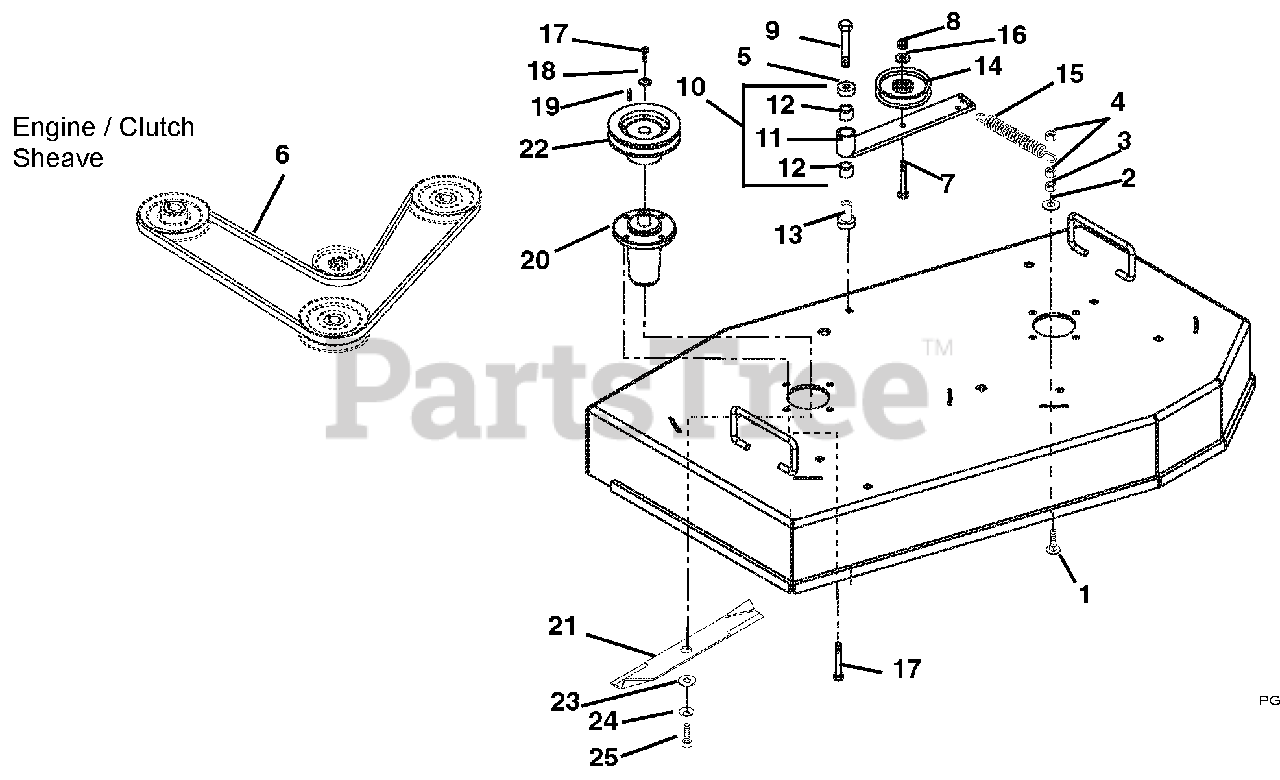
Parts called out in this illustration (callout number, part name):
1	@BLT-RDHDSQNK .38-16X1.50 G5YZ
2	@WSHR-LK .38X.094 REG YWZC
3	@NUT-HEX .38-16 YWZC
4	@NUT-LK-CTR .38-16 YWZC
5	WSHR-FL-STL .515X1.625X.250 YZ
6	V-BELT, HB-WRAPPED
7	@BLT-RDHDSQNK .38-16X3.00 G5YZ
8	@NUT-LK-CTR .38-16 YWZC
9	@BLT-HEX .50-13X3.75 GR5 YWZC
10	ASSEMBLY - IDLER PIVOT ARM
11	WMT - IDLER PIVOT ARM
12	BSHG, 1.00 X 1.125 X 1.937
13	BEARING, PEDESTAL
14	IDLER-FLAT 4.00X.38 (2.00 W)
15	SPRING, EXTENSION
16	SEAL, IDLER BEARING
17	BLT-HEX .38-16X1.0 GR8 YZ EP30
18	WSHR,FLT STL.406X1.50X.245YWZC
19	KEY, SQ .25X.25X1.00 RC 40-50
20	ASM,MAINT FREE SPINDLE
21	BLADE, 32" (16.25)
21	BLADE, 36" SAND, TUNGSTEN
22	WELDMENT, SPINDLE SHEAVE 5.00
23	WSHR-FLT .640X1.75X.250
24	WSHR-BLVL .669X1.535X.138
25	BLT-HEX .62-18X1.75 GR8 YWZC
